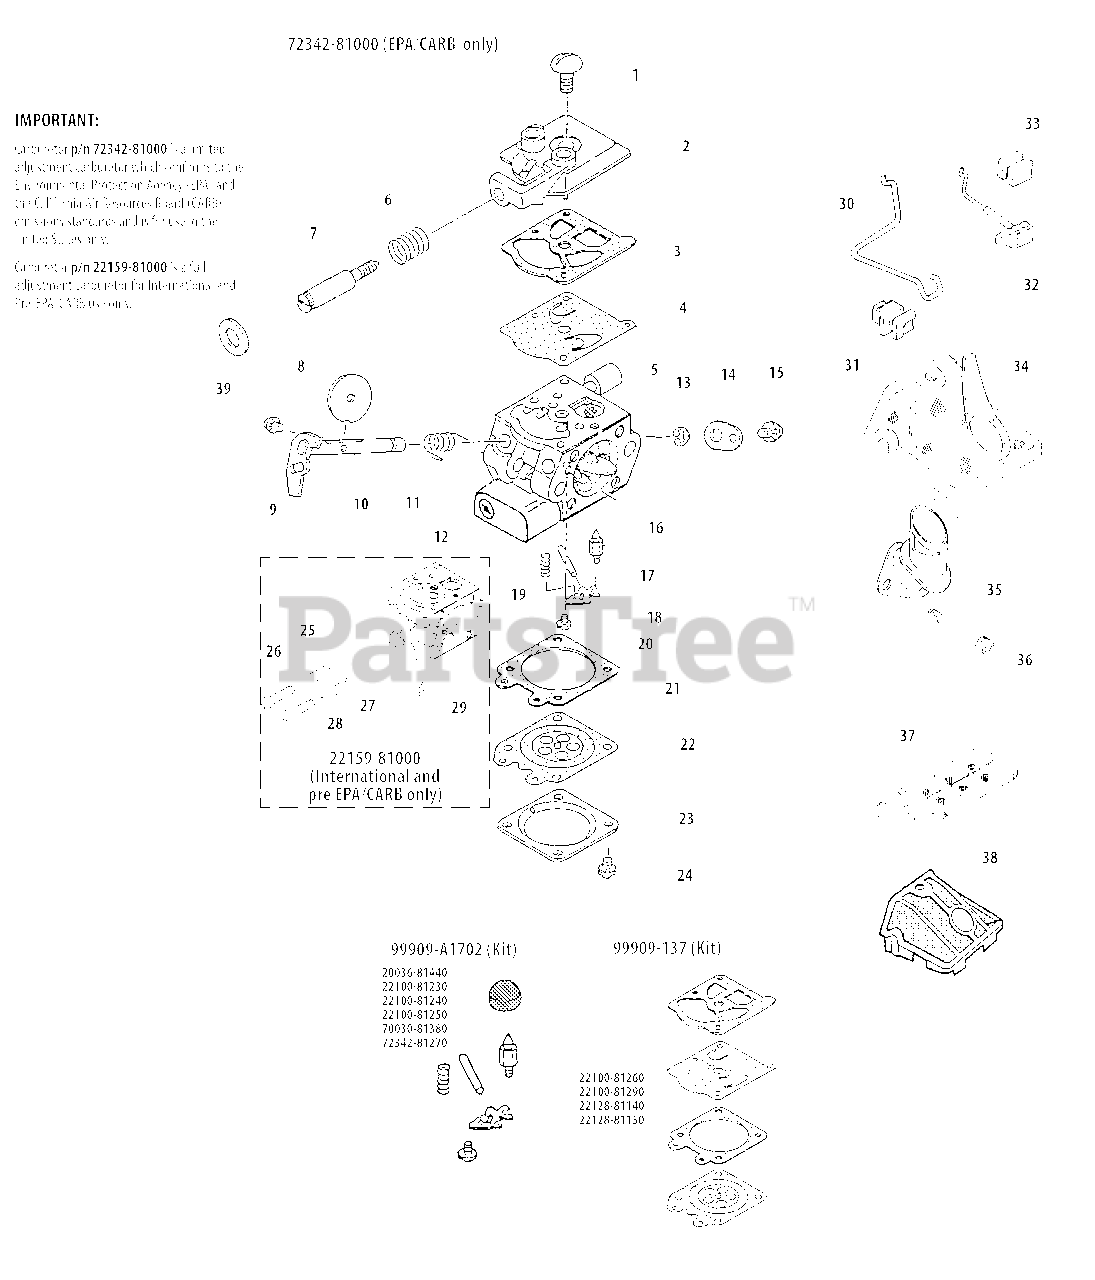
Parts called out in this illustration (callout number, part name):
1	SCREW
2	COVER ASSY, PUMP
3	GASKET, PUMP
4	DIAPHRAGM, PUMP
5	SCREEN, FUEL INLET
6	SPRING, IDLE ADJUST
7	SCREW, IDLE ADJUST
8	VALVE, THROTTLE
9	SCREW ASSY
10	SHAFT ASSY, THROTTLE
11	SPRING, THROTTLE RETURN
12	LIMITER CAP, L SPEED
13	E-RING
14	LEVER, THROTTLE
15	SCREW
16	VALVE, INLET NEEDLE
17	PIN, METERING LEVER
18	LEVER, METERING
19	SPRING, METERING LEVER
20	SCREW, METERING LEVER PIN
21	GASKET, METERING DIAPHRAGM
22	DIAPHRAGM, METERING
23	COVER, METERING DIAPHRAGM
24	SCREW
25	SPRING, NEEDLE
26	NEEDLE, LOW SPEED
27	SPRING, HIGH NEEDLE
28	NEEDLE, HIGH SPEED
29	SPRING, METERING LEVER
30	ROD, THROTTLE
31	GROMMET, ROD
32	ROD, CHOKE
33	GROMMET, CHOKE
34	FILTER, AIR
35	ELBOW
36	BOLT 5×40
37	FILTER, AIR
38	FILTER, FLOCKED AIR
39	SEAL, COLLAR
22159-81000	CARBURETOR
72342-81000	CARBURETOR
99909-137	DIAPHRAGM/GASKET KIT
99909-A1702	REPAIR KIT
